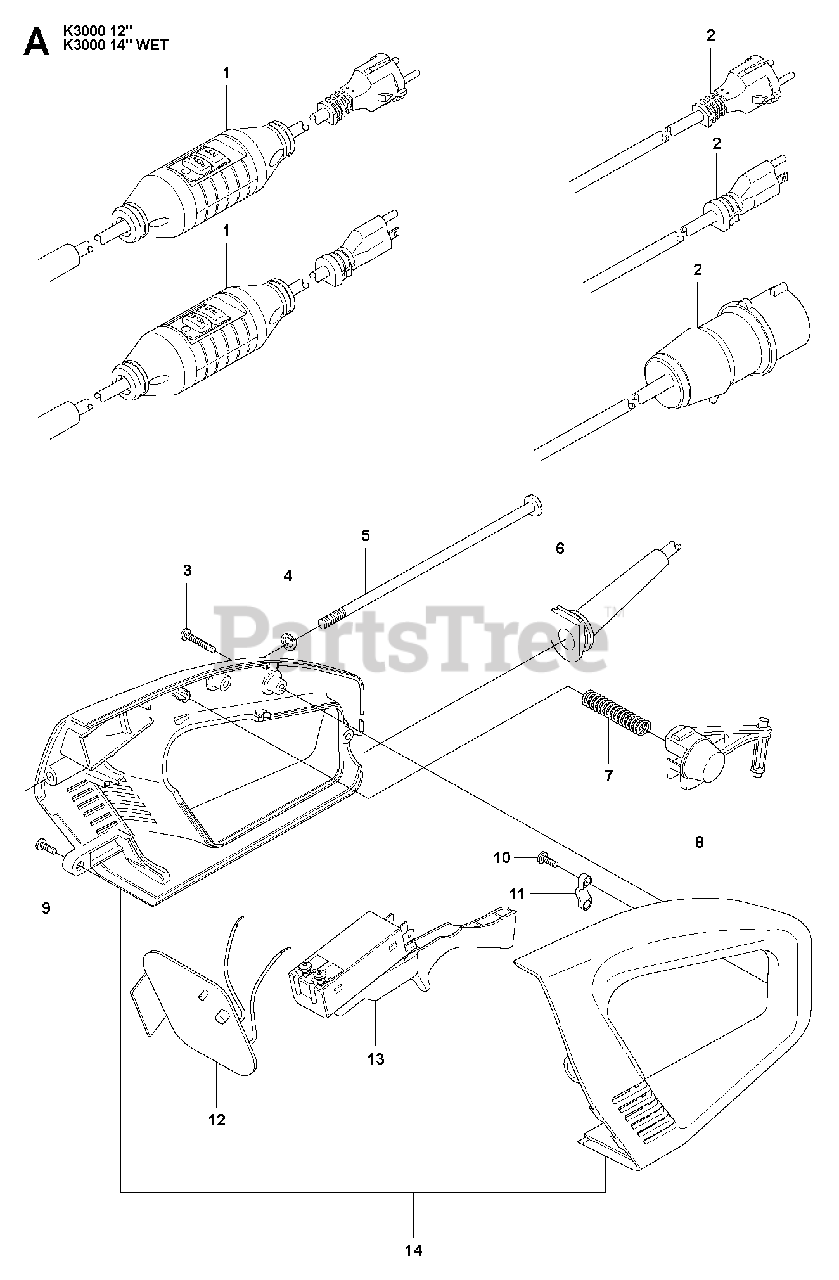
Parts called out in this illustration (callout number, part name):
1	CABLE110V JP, USA
2	CABLE ASSY230V
2	CABLE110V JP, USA
4	SPRING WASHER
6	CABLE SLEEVE230V
7	SPRING
8	LOCKING BUTTON
9	SCREW CRPANM
12	ENGINE PROTECTION110V
12	ENGINE PROTECTION230V
14	HANDLE ASSY
